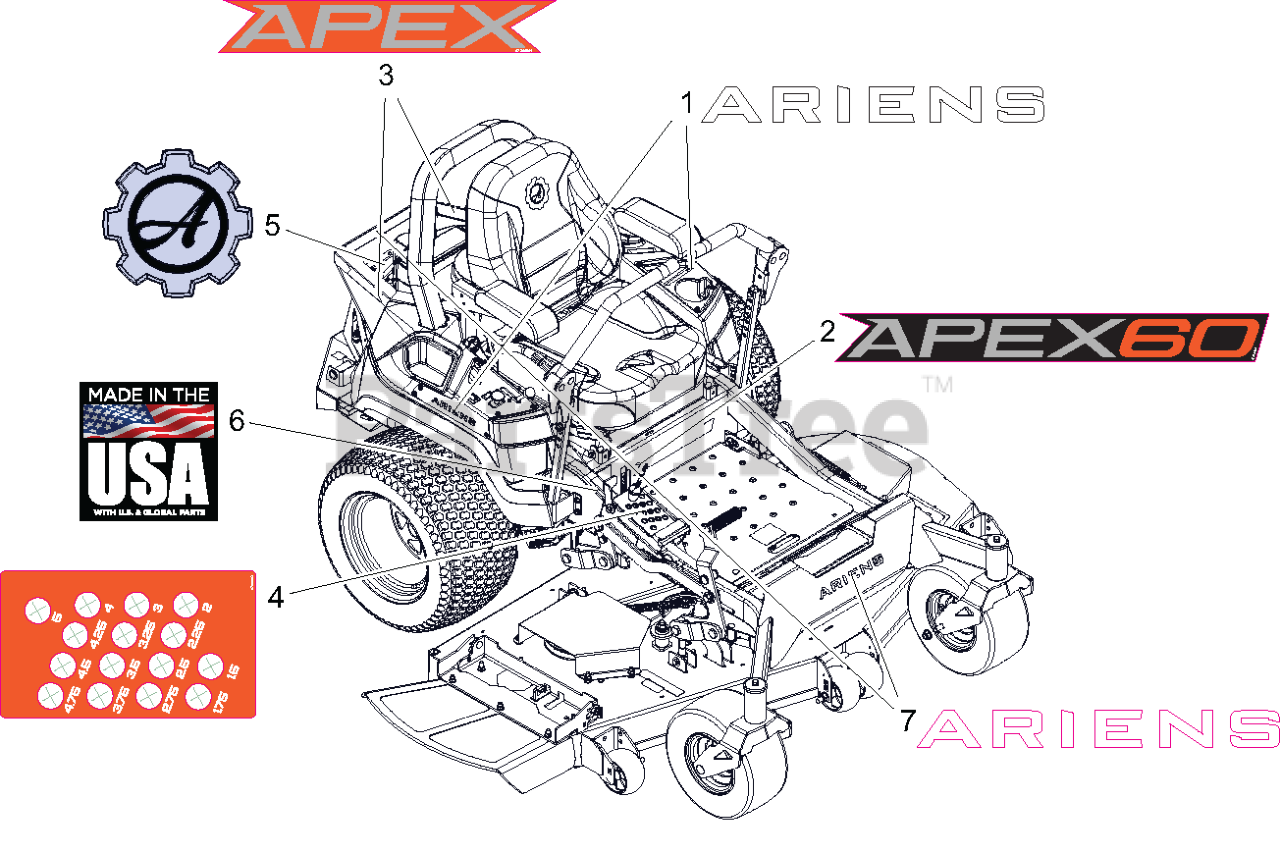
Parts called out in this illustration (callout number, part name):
1	DECAL, ARIENS (6.50")
2	DECAL, 60" APEX KICKPLATE
3	DECAL, APEX FENDER
4	DECAL, ARIENS HOC
5	DECAL- ARIENS GEAR BADGE
6	DECAL, MADE IN USA
7	DECAL, ARIENS - BADGE
